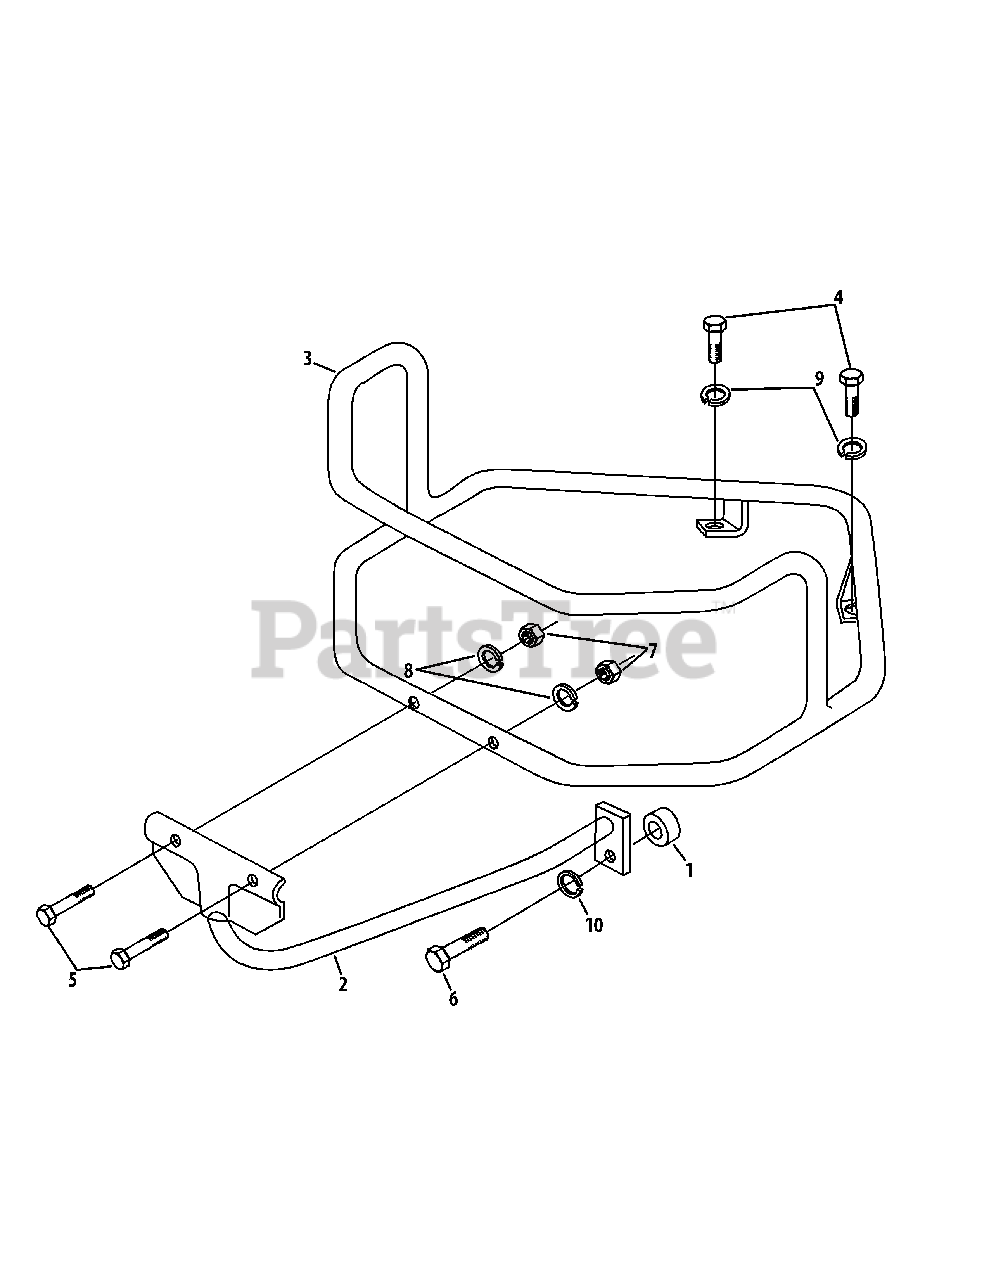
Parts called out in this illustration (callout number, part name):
1	Spacer, 1.0 x .546 x .5
2	Bottom Bumper Brace
3	Bumper Guard
4	Hex Screw, 3/8"-16 x 1.00
5	Hex Screw, 5/16"-18 x 1.50
6	Hex Screw, 1/2"-13 x 1.50
7	Hex Nut, 5/16"-18
8	Lock Washer, 5/16"
9	Lock Washer, 3/8"
10	Lock Washer, 1/2"
